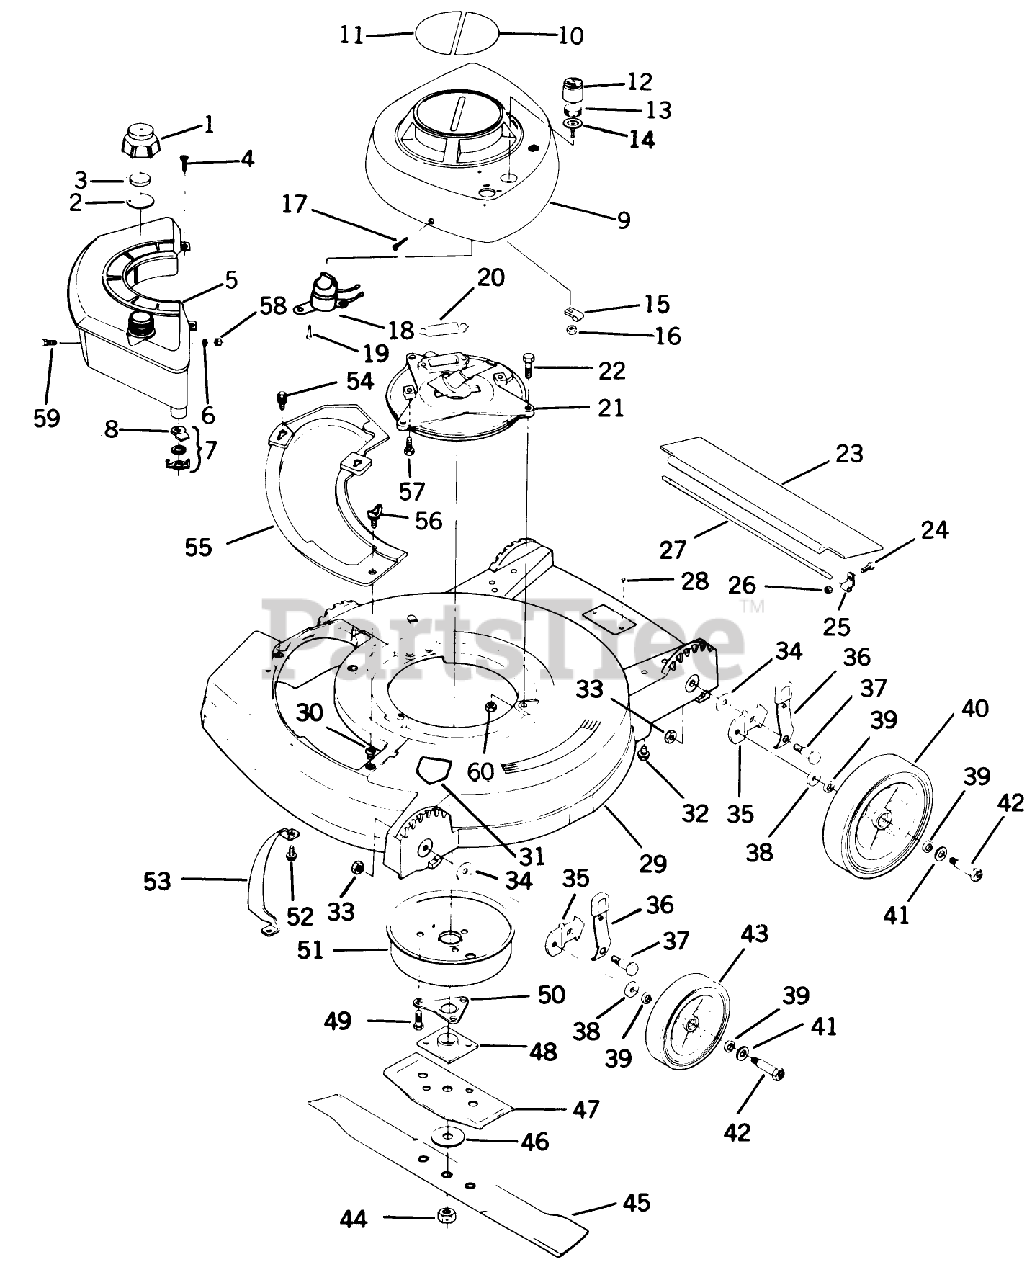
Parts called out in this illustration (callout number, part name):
2	GASKET S
3	BAFFLE - FOAM SM
4	SCREW F
7	SHUT OFF VALVE KIT
13	FILTER S
16	LOCKNUT S
17	SCREW F
22	SCREW
25	CLAMP ROD KMC
26	LOCKNUT E
27	ROD 21" ADVANCE
32	SCREW
33	LOCKNUT
34	WASHER
38	WASHER WROUGHT
39	WASHER
41	SPACER
42	BOLT WHEEL
43	WHEEL & TIRE KIT
44	NUT-BLADE
46	WASHER
48	PLATE AND COLLAR ASM
49	SCREW
50	SUPPORT F
53	BAR-TOE
56	WING SCREW LAWRE
57	SCREW V
60	NUT-LOCK F
